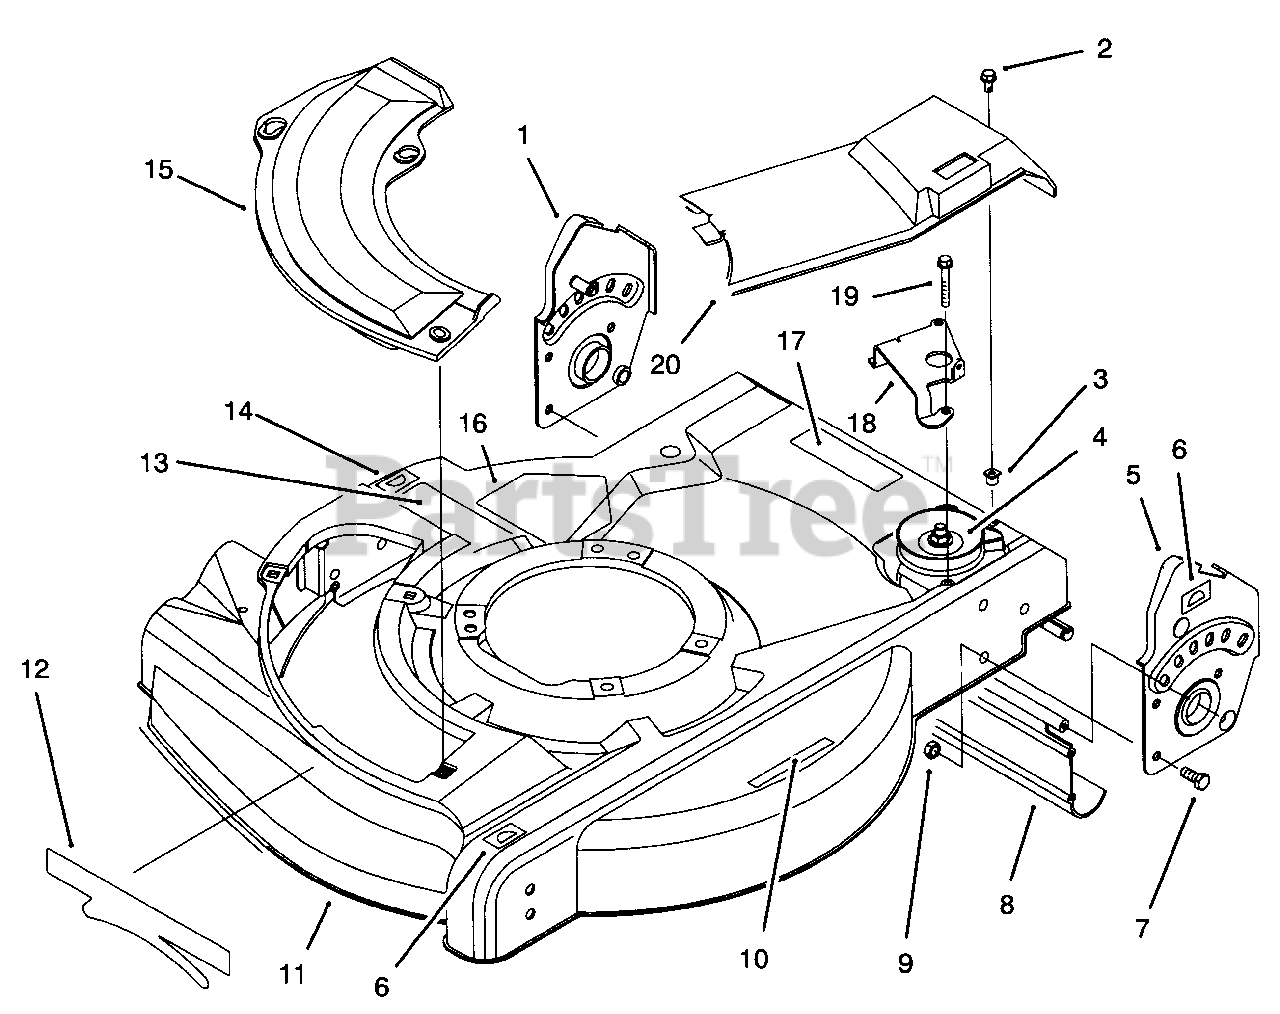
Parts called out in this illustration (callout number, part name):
1	Bracket-Handle R.H.
2	Screw-Phillips Hd.
3	Grommet
4	Gear Case Assembly
5	Bracket-Handle L.H.
6	Decal-H.O.C.
7	Screw-Hex Hd. Cap
8	Shield-Trailing
9	Nut-Lock
10	Decal-Warning
11	Housing
12	Decal-Deck
13	Decal-Discharge
14	Decal H.O.C.
15	Plate-Cover
16	Decal-Danger
17	Decal-Warning
18	Guide-Transmission
19	Screw-Hex Hd. Cap
20	Cover-Drive
